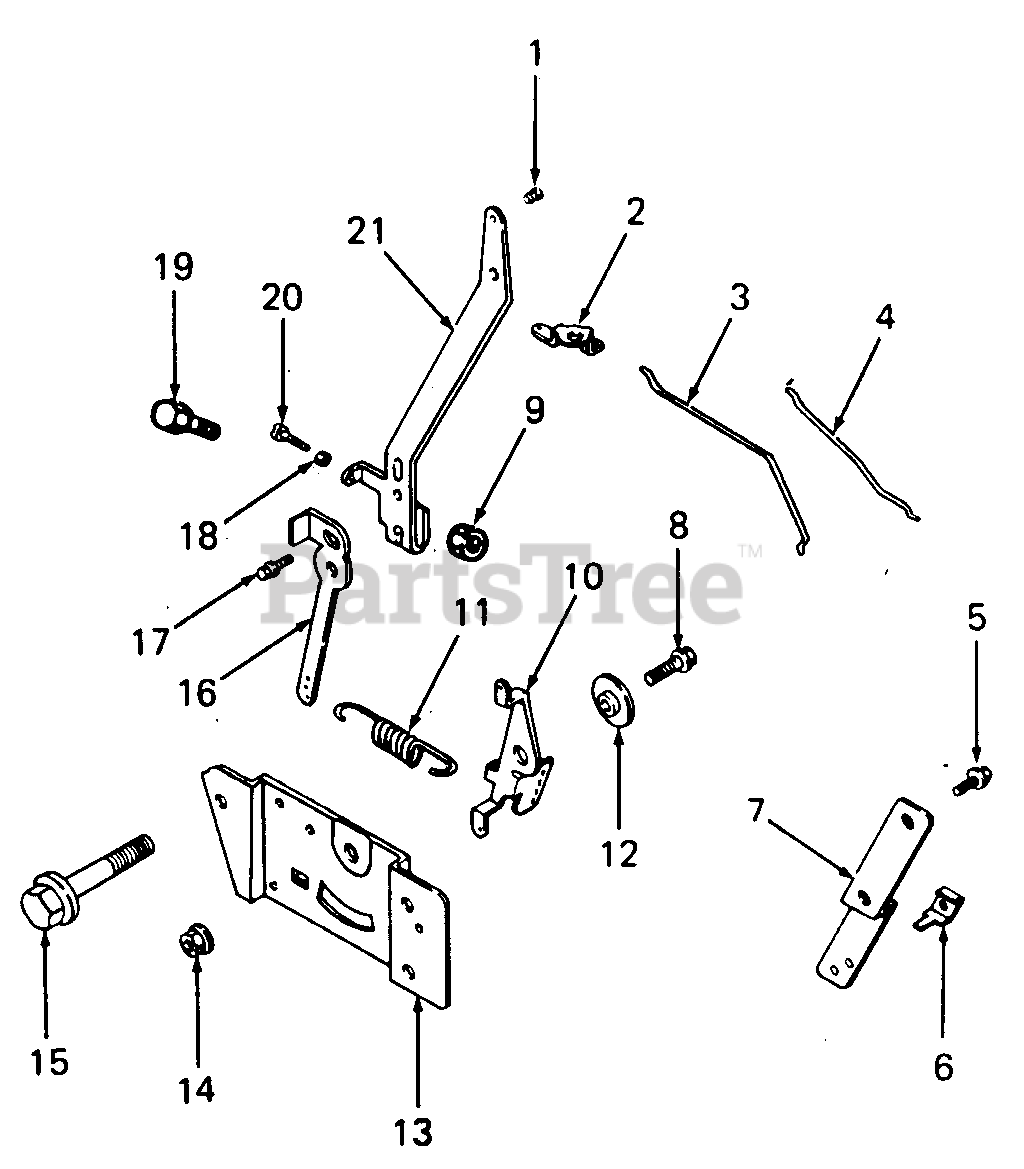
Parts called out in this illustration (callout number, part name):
1	Bushing, Linkage Retaining
2	Lever, Choke
3	Linkage, Choke
4	Linkage, Throttle
5	Screw, Choke Lever, M5 X 0.8 X 10
6	Clamp, Cable
7	Bracket, Choke Mount
8	Screw, M8 X 0.8 X 16
9	Nut, Governor Arm, M6 X 1.0
10	Lever, Throttle
11	Spring, Governor
12	Spacer, Shoulder
13	Plate, Control
15	Screw, Hex Hd, M6 X 1.0 X 20
16	Lever, Governor
17	Screw, Governor Lock
18	Nut, Hex
19	Screw, Governor Lock, M6 X 1.0 X 25
20	Screw, Governor Adj
21	Lever, Governor
